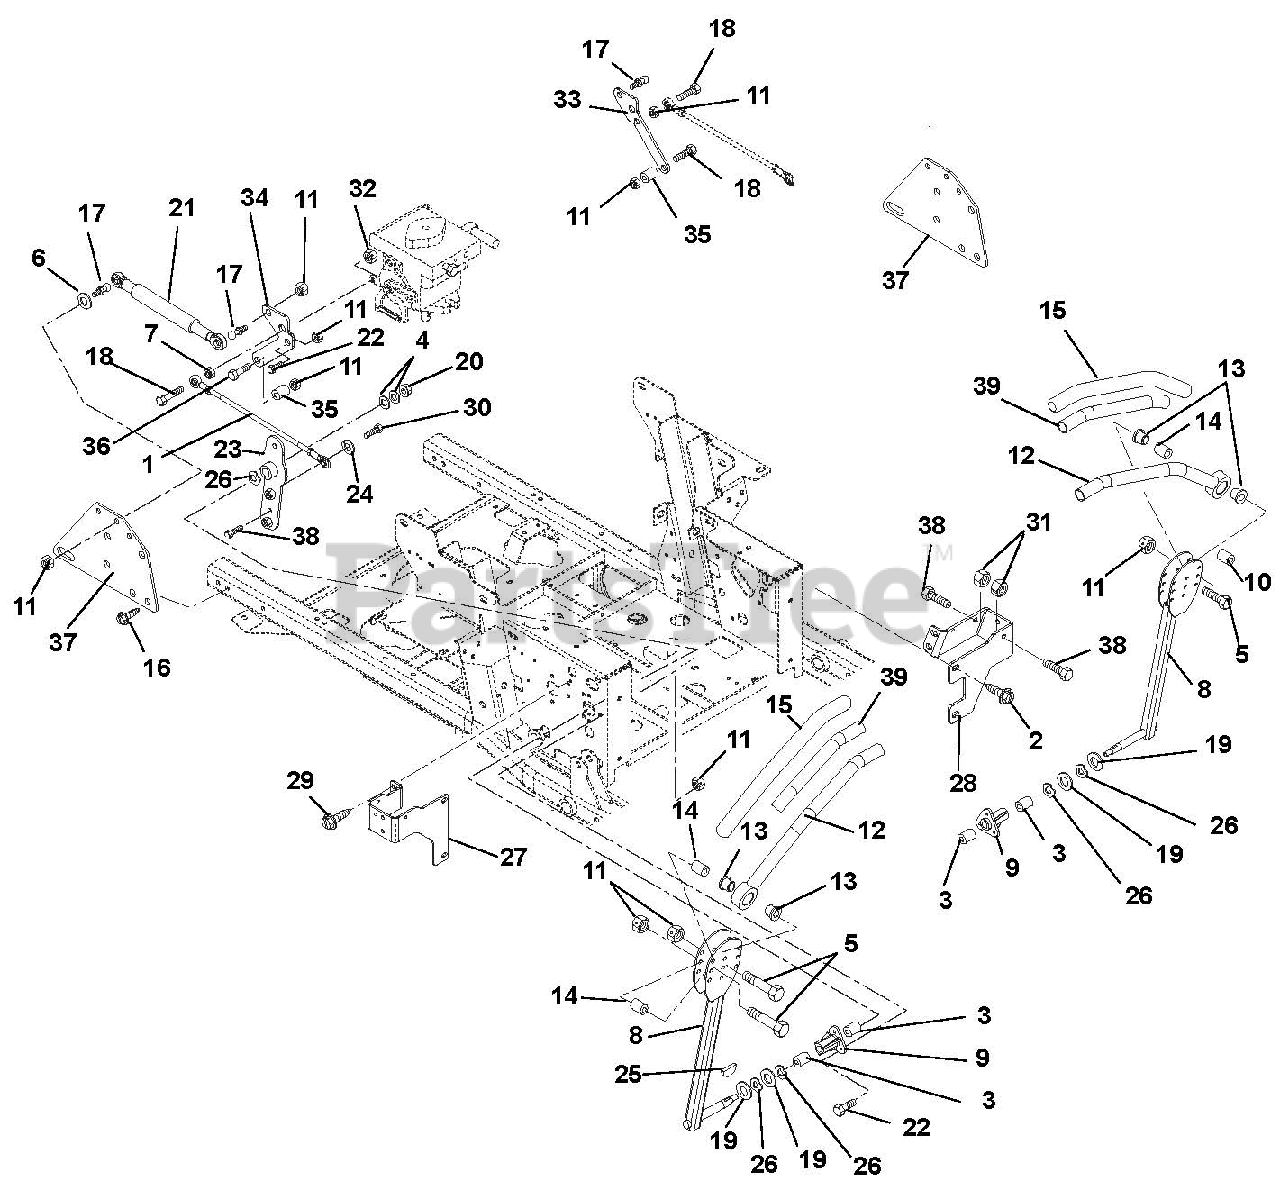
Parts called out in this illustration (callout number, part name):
1	Assembly, Steering Rod .38 Rod x 7.60
2	Screw, Tapping Hex Washer Head .38-16 x .75
3	Bushing .625 x .75 x .50
4	Washer, Flat Steel .403 x .812 x .065
5	Bolt, Hex .31-18 x 1.75 Grade 5
6	Washer, Flat Steel .344 x .688 x .065
7	Nut, Hex .38-16
8	Control Arm
9	Bushing, Flange
10	Bushing, Eccentric .31 x .75 .97
11	Nut, Locking Top Flange .31-18
12	Handle Weldment, Left Hand
12	Handle Weldment, Right Hand
13	Bushing, Flange Nylon .762 x 1.48 x .44
15	Grip, Handlebar
16	Screw, Tapping Hex Washer Head .31-18 x .50
17	Stud, Ball
18	Bolt, Hex .38-16 x 1.50 Grade 5
19	Washer, Flat Steel .63 x 1.005 x .062
20	Nut, Locking Top Flange .38-16
21	Damper, Control
22	Bolt, Hex .31-18 x .75 Grade 5
23	Weldment, Pivot Arm
24	Washer, Locking .38 x .094 Regular
25	Key, Woodruff .13 x .63
26	Washer, Wave
27	Stop, Steering Right Hand
28	Stop, Steering Left Hand
29	Screw, Tapping Hex Washer Head .38-16 x .50
30	Bolt, Hex .38-16 x 1.25 Grade 5
31	Nut, Hex Jam .375-16
32	Nut, Locking Center .38-16
33	Bracket, Left Hand
34	Bracket, Right Hand
35	Spacer .318 x .43 x .375
36	Bolt, Hex .31-18 x 1.25 Grade 5
37	Bracket, Damper
38	Bolt, Hex .375-16 x 1.75 Full Thread
39	Tube, .88 ID x 1.00 OD x 10.75
